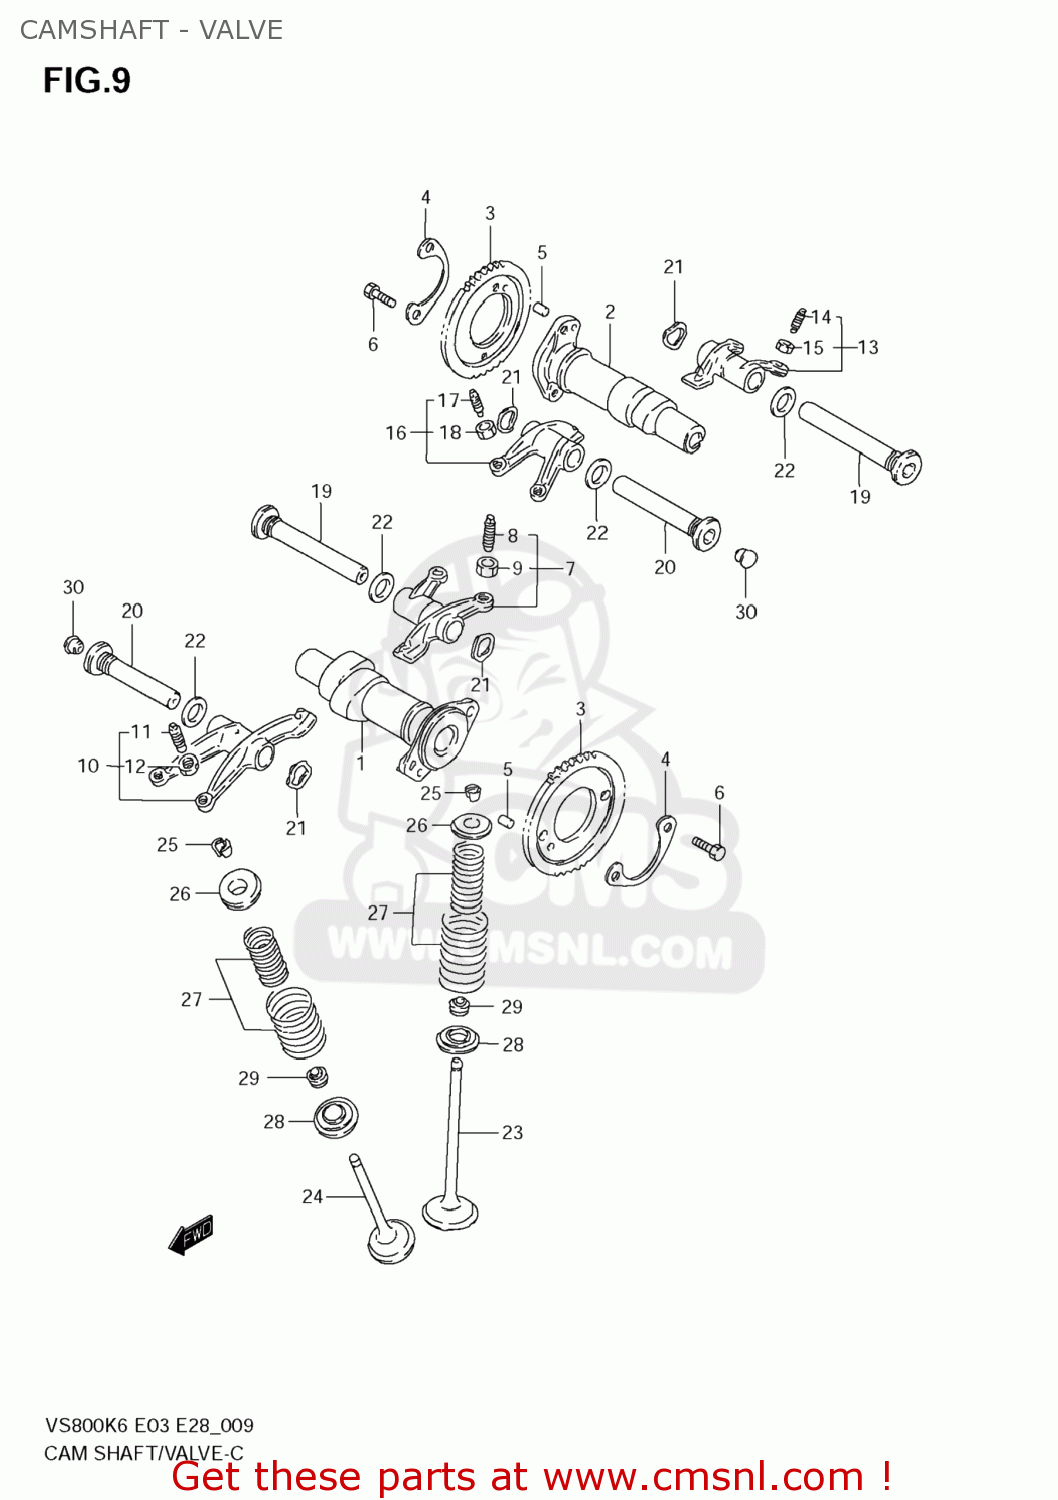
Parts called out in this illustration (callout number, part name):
1	CAMSHAFT,FR
2	CAMSHAFT,RR
3	SPROCKET,CAMSHAFT(NT:42)
4	WASHER,SPROCKET
5	PIN
6	BOLT(6X12.5)
7	ARM,INTAKE VALVE ROCKER FR
8	SCREW,TAPPET ADJUSTING
9	NUT,ADJUSTING SCREW
10	ARM,EXHAUST VALVE ROCKER FR
11	SCREW,TAPPET ADJUSTING
12	NUT,ADJUSTING SCREW
13	ARM,INTAKE VALVE ROCKER RR
14	SCREW,TAPPET ADJUSTING
15	NUT,ADJUSTING SCREW
16	ARM,EXHAUST VALVE ROCKER RR
17	SCREW,TAPPET ADJUSTING
18	NUT,ADJUSTING SCREW
19	SHAFT,VALVE ROCKER ARM
20	SHAFT,VALVE ROCKER ARM
21	WASHER
22	GASKET(13.8X18.8X4.8) (NAS)
23	VALVE,INTAKE
24	VALVE,EXHAUST
25	COTTER,VALVE
26	RETAINER,VALVE SPRING
27	SPRING SET,VALVE
28	SEAT,VALVE SPRING
29	SEAL,OIL(5.5X11X8.2)
30	CAP(OD:10)
